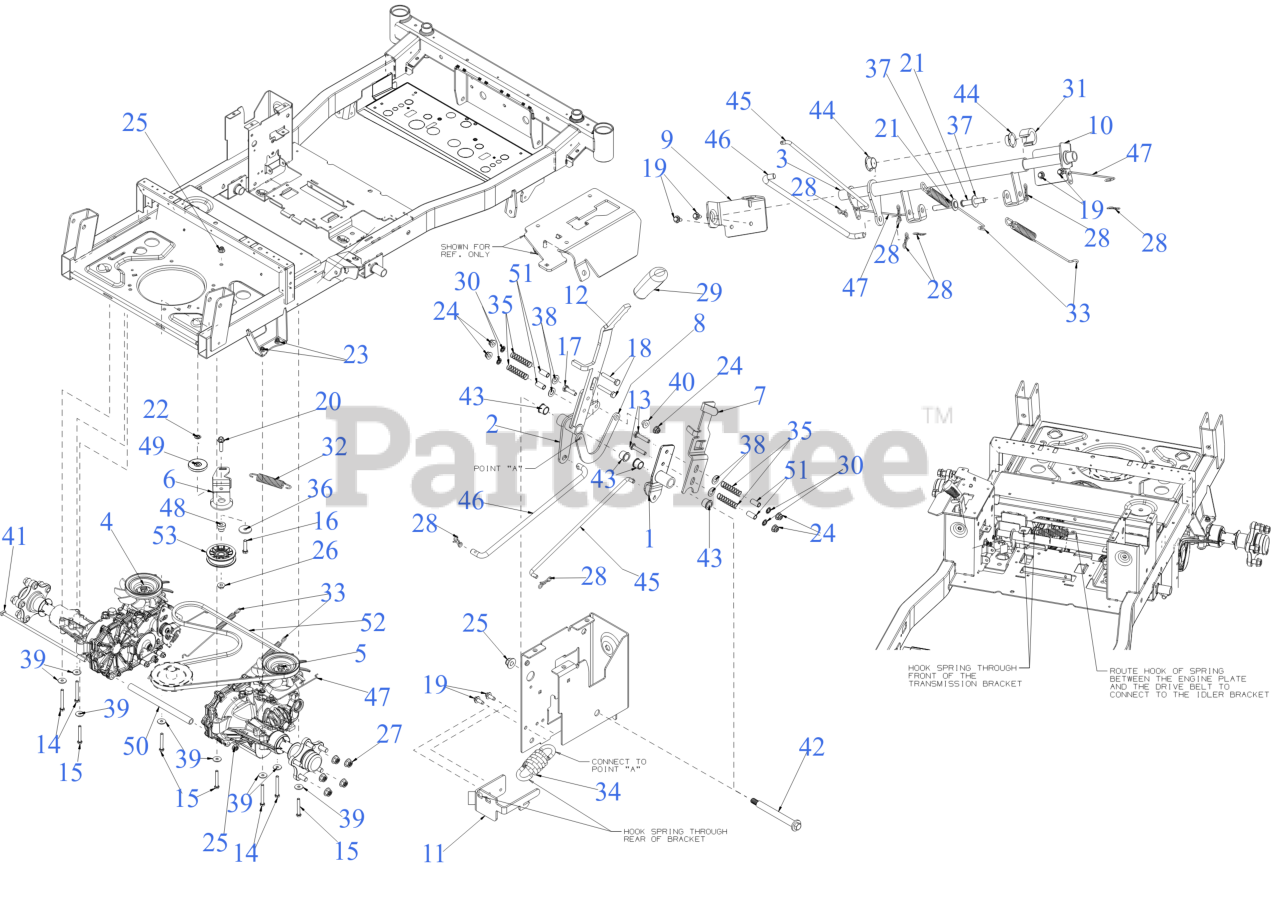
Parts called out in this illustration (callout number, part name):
1	BYPASS LEVER PIVOT ARM
2	PARK BRAKE PIVOT ARM
3	BRAKE PIVOT SHAFT
4	HYDRO TRANSMISSION (LH)
5	HYDRO TRANSMISSION (RH)
6	HYDRO DRIVE IDLER BRACKET
7	TRANSMISSION BYPASS LEVER
8	OVER CENTER LINK
9	BRAKE SHAFT SUPPORT (RH)
10	BRAKE SHAFT SUPPORT (LH)
11	SPRING MOUNTING BRACKET
12	PARK BRAKE LEVER
13	HEX SCREW 1/4-20 x 1.25
14	HEX SCREW 5/16-18 x 2.75
15	HEX SCREW 5/16-18 x 2.25 GR5
16	SCREW 3/8-16 x 1.50
17	SCREW 1/4-20 X1.00 GR5
18	SCREW 1/4-20 x 1.50 GR.5
19	SCREW M6-1 x .625
20	HEX HEAD BOLT (3/8-16:1.50 GR8)
21	CLEVIS PIN 3/8 x 1.87
23	FLANGE LOCK NUT 5/16-18
24	FLANGE LOCK NUT
26	FLANGE LOCK NUT
27	HEX FLANGE NUT 1/2-20 GR8
28	BOW TIE COTTER PIN 1/4-5/16
30	RETAINER-BOLT .25ID x .50OD
31	SPACER: .76ID x .75
32	EXTENSION SPRING .925 x 5.37
33	EXTENSION SPRING .60 DIAx9.09
34	EXTENSION SPRING 1.09x3.25
35	COMPRESSION SPRING
36	FLAT WASHER .390x1.500x.134
37	FLAT WASHER
38	WASHER THRUST .375X.70X.030
39	FLAT WASHER 1.0 OD:.331 ID
40	SHOULDER SPACER
41	SUPPORT TUBE ROD
42	SHOULDER SCREW .491x3.937 3/8-16
43	FLANGE BUSHING
44	FLANGE BEARING .75 x 1.125 x .375
45	BYPASS LINK
46	BRAKE LINK
47	HYDRO BYPASS ROD .100 DIA
48	SHOULDER SPACER
49	SHOULDER SPACER
50	SUPPORT TUBE
51	SPACER .252x.350x.760
52	TRANSMISSION DRIVE BELT A x 67
53	FLAT IDLER PULLEY 3.00 OD
